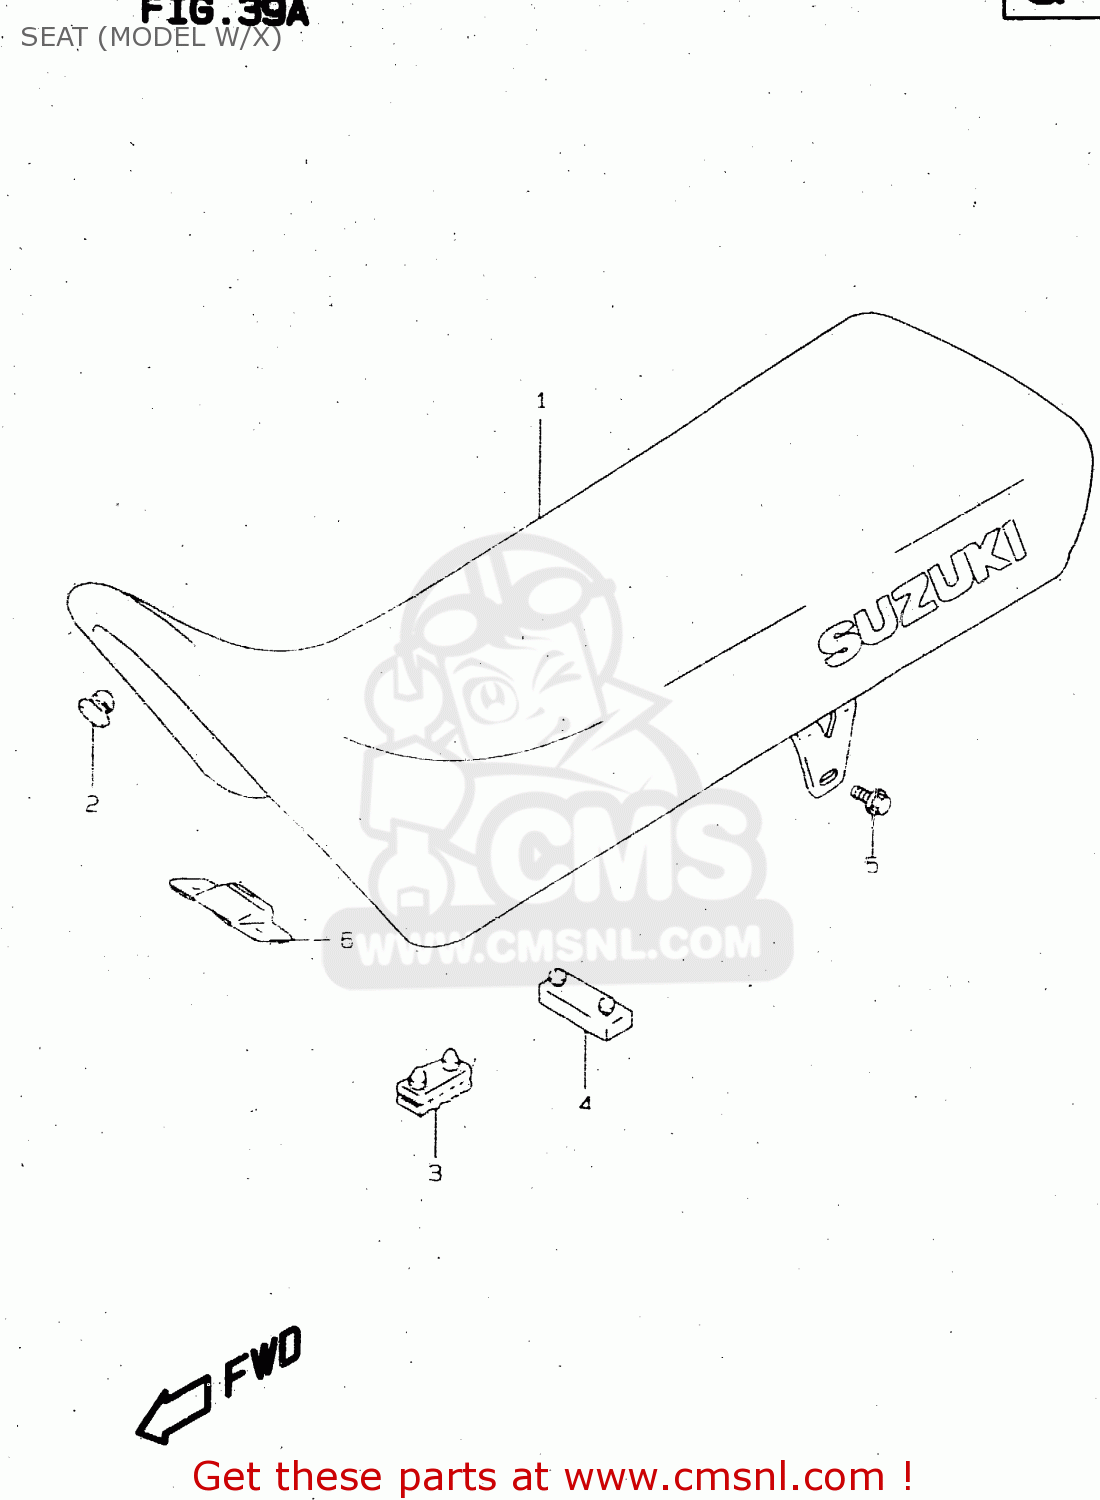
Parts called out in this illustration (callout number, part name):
1	SEAT SET
2	CUSHION
3	CUSHION,SEAT(40X20X15)
4	CUSHION,SEAT
5	BOLT
6	PLATE,SEAT FR HOOK
